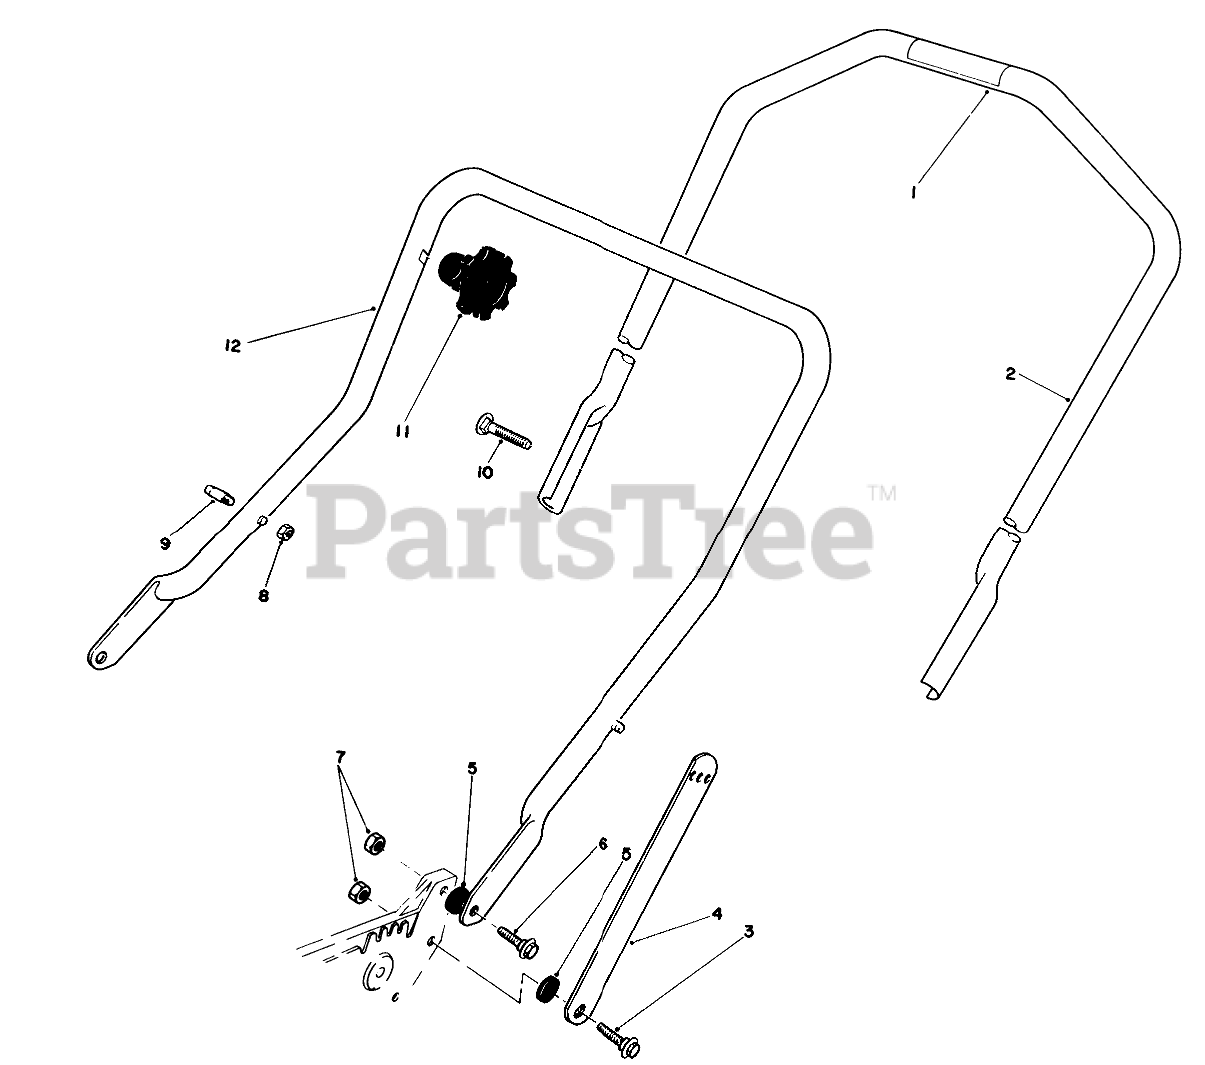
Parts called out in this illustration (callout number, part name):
1	Decal-Danger
2	Handle-Upper (Incl. Ref. #1)
3	SCREW-SHOULDER
4	Handle Latch
5	SPACER
6	SCREW-SHOULDER
7	NUT-LOCK, NI
8	NUT-LOCK, NI
9	HANDLE PIN
10	5/16-18 X 2 HNDLE SCREW
12	Handle-Lower
